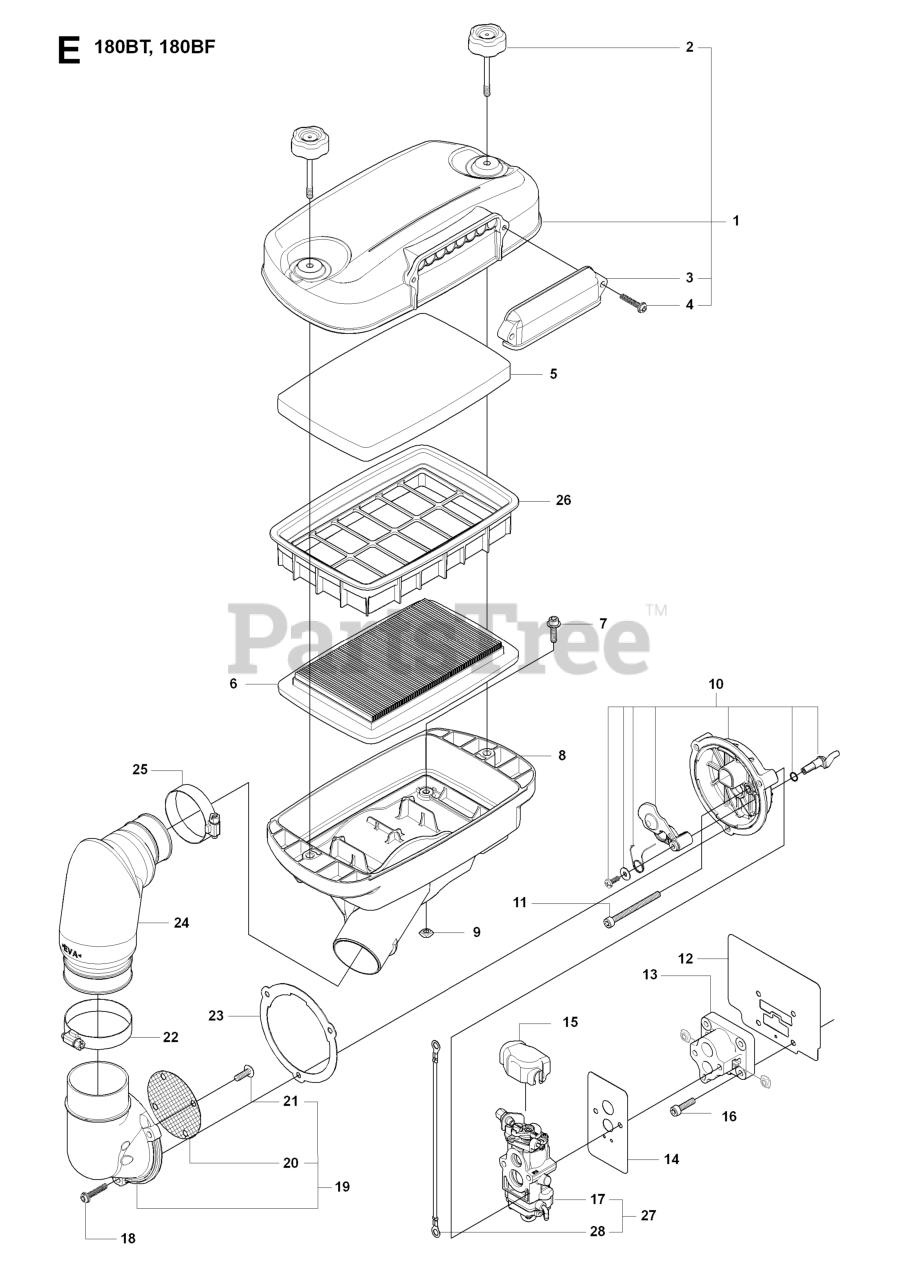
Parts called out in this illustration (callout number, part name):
1	COVER ASSY
4	SCREW
5	ELEMENT T401282321
6	ELEMENT T401282311
7	BOLT
10	CUP
11	BOLT
12	GASKET
13	INSULATOR
14	GASKET
15	COVER
16	BOLT
17	CARBURETOR-A
18	SCREW
19	COVER-A
21	SCREW
22	CLAMP(F64)
23	GASKET
25	CLAMP(F64)
27	CARBURETOR SET
28	CORD
